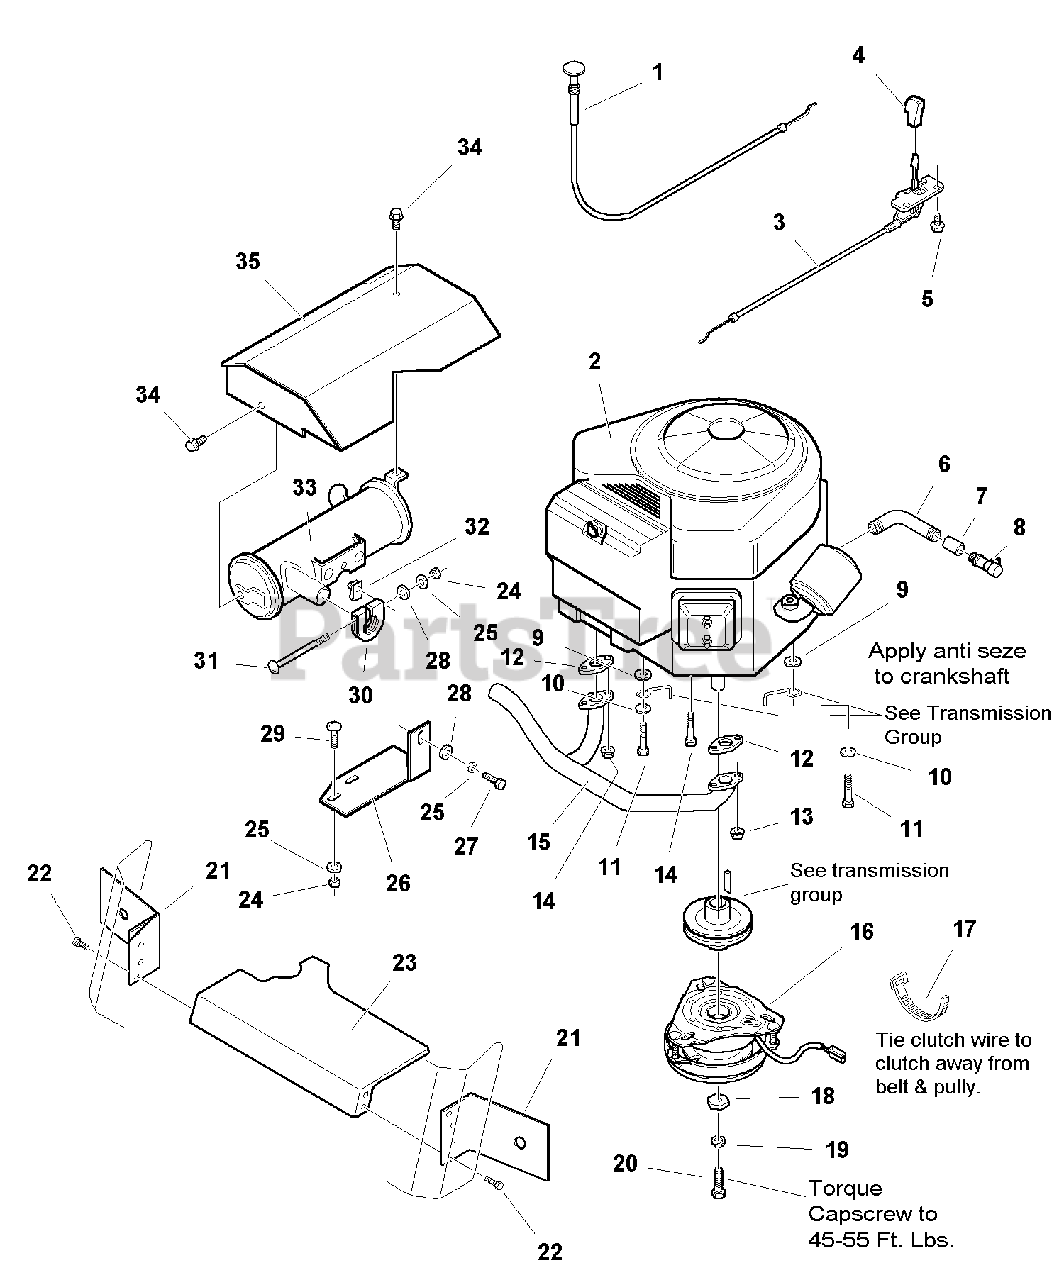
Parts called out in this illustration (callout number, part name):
1	CHOKE CONTROL ASSEMBLY
3	THROTTLE CONTROL ASSEMBLY
4	KNOB, Throttle
5	CAPSCREW, Plastite, 1/4-10 x 1/2
6	PIPE, 3/8, 90Ý
7	COUPLER, 3/8
8	VALVE, Oil Drain
9	WASHER, Plain
10	WASHER, 3/8
11	CAPSCREW, Taptite, 3/8-16 x 2
12	GASKET, Muffler
13	NUT, Hex Flange
14	CAPSCREW, Taptite, 3/8-16 x 1 1/2
15	PIPE, Exhaust
16	CLUTCH, Electric
17	TIE, Self Locking
18	WASHER, Hex
19	LOCKWASHER, 7/16
20	CAPSCREW, Hex, 7/16-20 x 3-1/4
21	SHIELD, Heat
22	CAPSCREW, Hex, Thd. Form, #10-24 x 1/2
24	NUT, Hex, 5/16-18
25	LOCKWASHER, 5/16
26	SUPPORT, Muffler
27	CAPSCREW, Hex, 5/16-18 x 1
28	WASHER, 5/16
29	CARRIAGE BOLT, 5/16-18 x 3/4
30	CLAMP, Muffler
31	CARRIAGE BOLT, 5/16-18 x 2 3/4
32	NUT, Speed, 5/16-18
33	MUFFLER ASSEMBLY
34	CAPSCREW, Hex, Taptite, 5/16-18 x 1/2
35	SHIELD, Muffler
